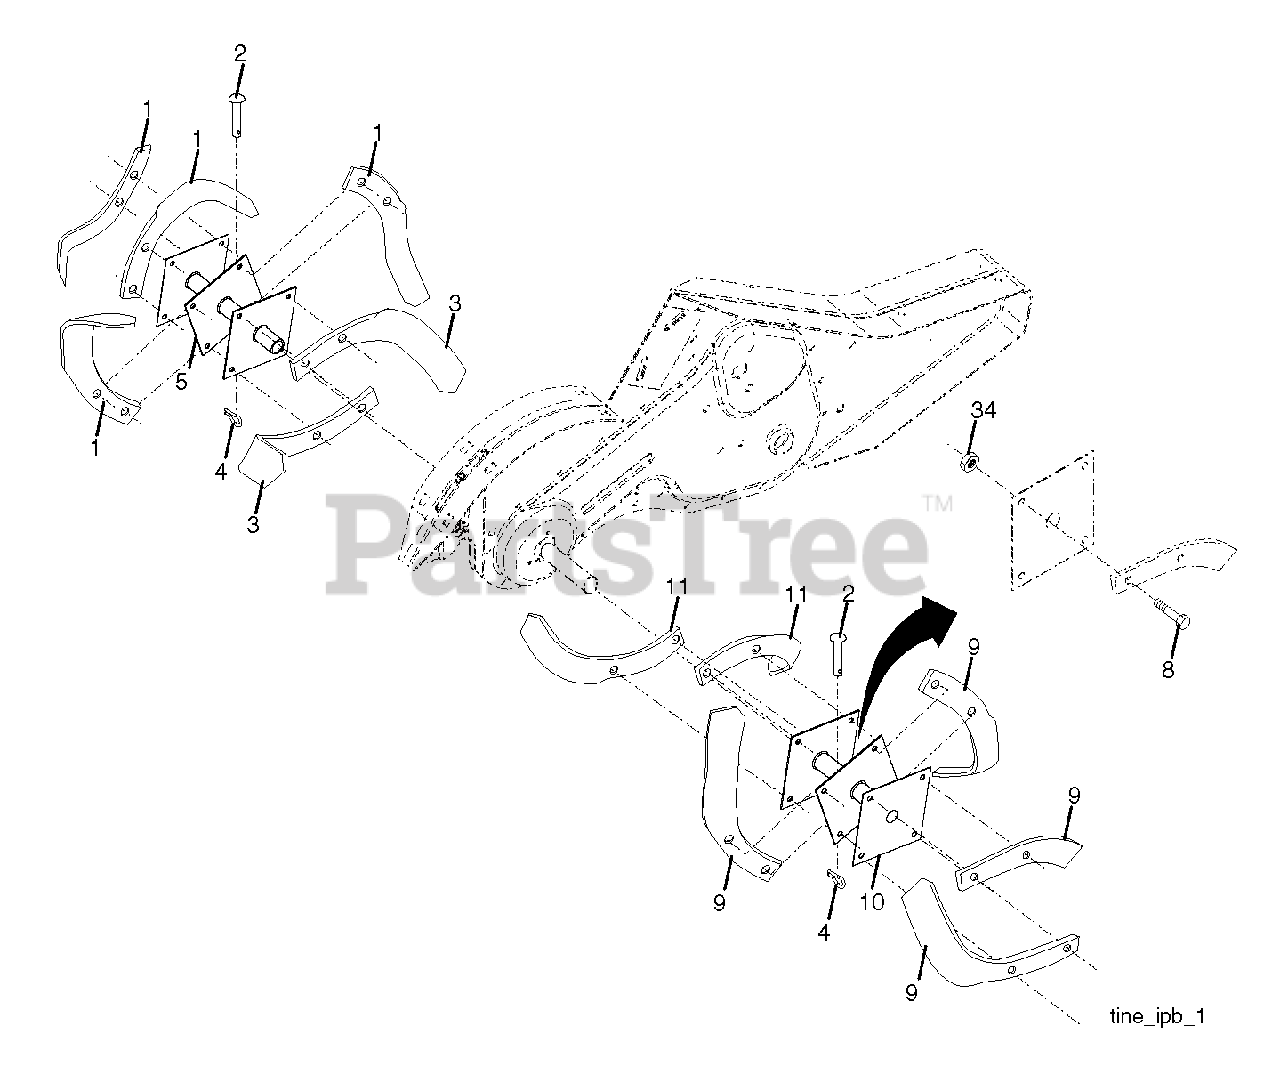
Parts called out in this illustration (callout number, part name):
1	TINE TI
2	CLEVIS PIN
3	TINE.LH.12"(72L)
4	SPRING RETAINER
5	HUB.&.PLATE.ASM.LH
8	BOLT.HEX.001X20.37-24X1.ZINC
9	TINE TI
10	HUB & PLATE ASM RH
11	TINE.RH.12"(72R)
34	NUT CROWNLOCK 3/8-24
